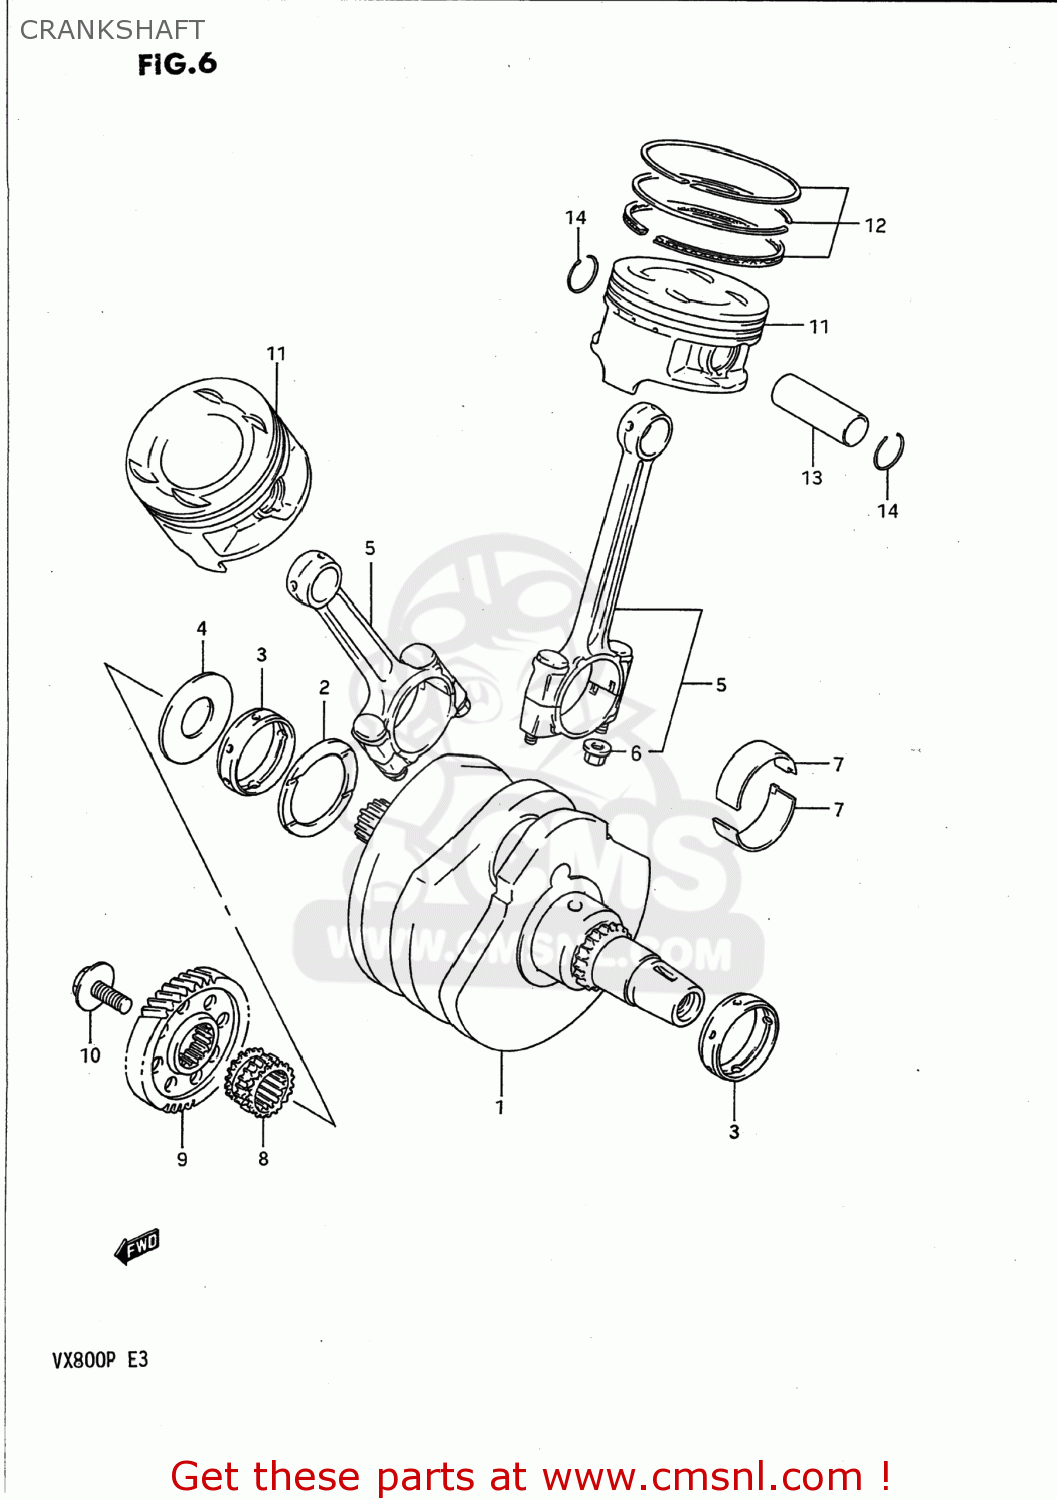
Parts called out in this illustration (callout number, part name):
1	CRANKSHAFT SET
2	WASHER(48.1X64X1.94)
3	METAL,CRANKSHAFT
4	WASHER,CRANK THRUST
5	CONNECTING ROD ASSY
6	NUT
7	BEARING,CRANK PIN
8	SPROCKET,CAM CHAIN DRIVE,R
9	GEAR,PRIMARY DRIVE
10	BOLT(12X28)
11	PISTON
12	RING SET,PISTON
13	PIN,PISTON
14	CIRCLIP,PISTON PIN
